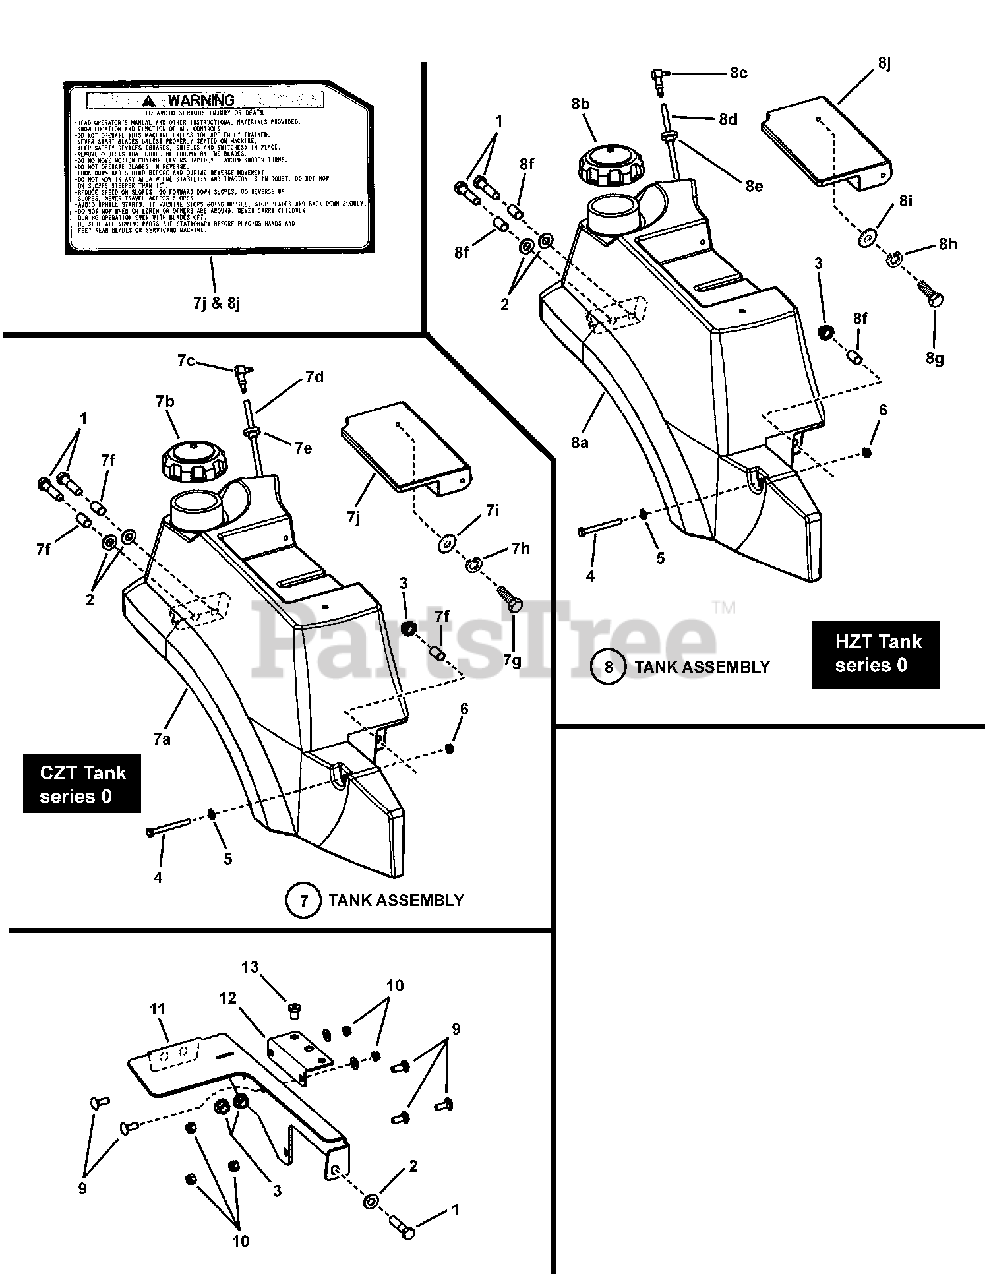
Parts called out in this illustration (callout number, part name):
1	SCREW, 7/16-14 x 2" Hex Head Cap, GR 5
2	WASHER, 1/2" Flat SAE
3	NUT, 7/16-14 HEX NYLON LOCK
4	BOLT, 5/16-18 X 2-1/2" GD5 YZ
5	WASHER, 5/16" Flat
6	NUT, 5/16-18 HEX NYLON LOCK
7	ASSEMBLY, R.H. Tank CZT (incl. 10 items shown below)
8	ASSEMBLY, R. H. Tank HZT (incl. 10 items shown below)
9	BOLT, 3/8-16 x 1" Square Neck Carriage, GR 5
10	NUT, 3/8-16 HEX NYLON LOCK
11	WELDMENT, R.H. Tank Bracket
12	BRACKET, Auxiliary Fuel Valve
13	WELL-NUT, 1/4-20 x 53/64
